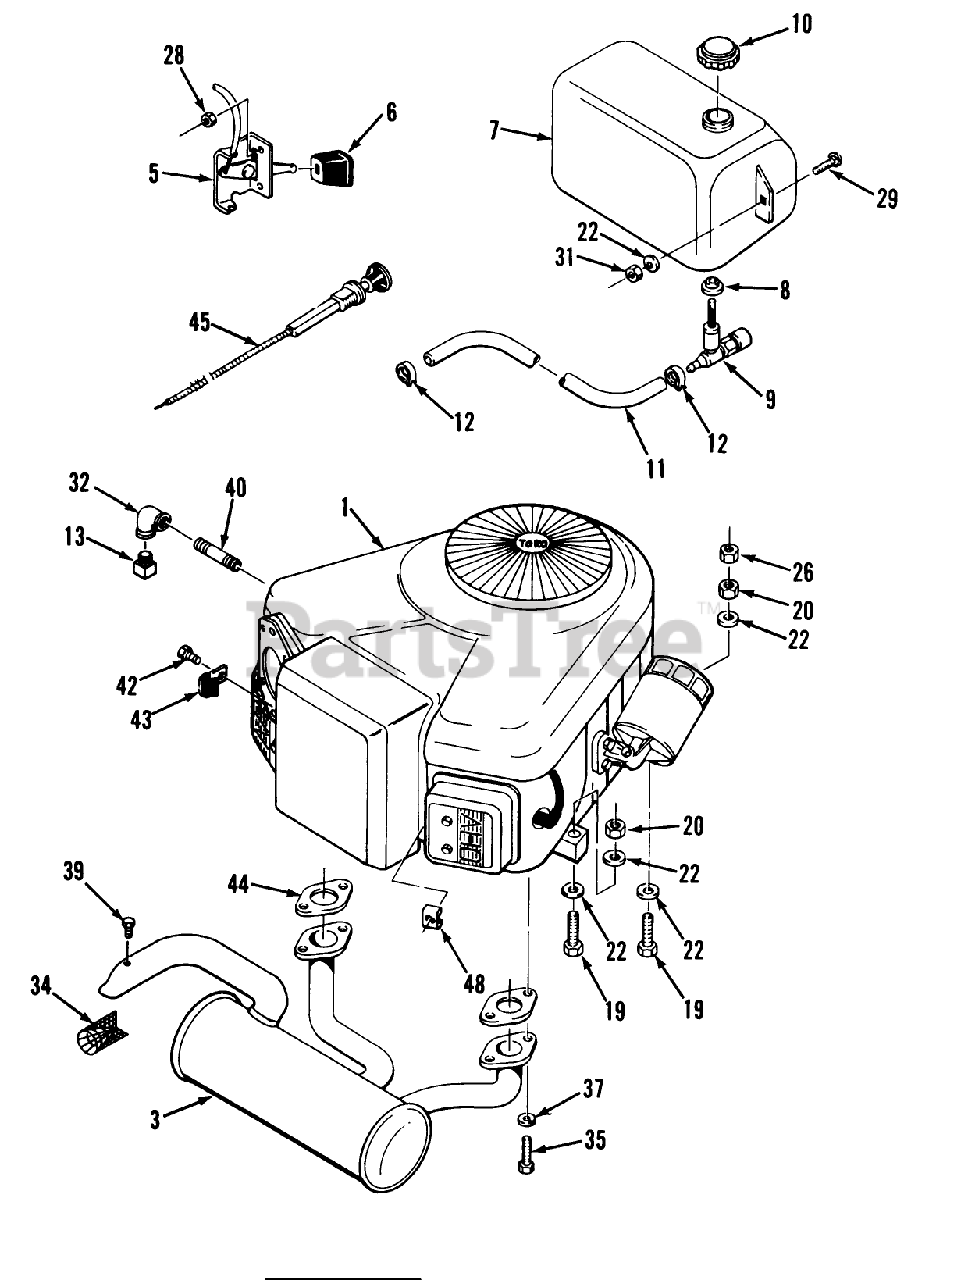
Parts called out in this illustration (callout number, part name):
3	MUFFLER-16 VANGUARD
5	CONTROL-THROTTLE
10	CAP GAS
22	WASHER 5/16 SAE
32	ELBOW 3/8 90 DEG
35	SHCS 5/16-18X.625
42	HHCS M8X1.25X20
43	J-CLIP
